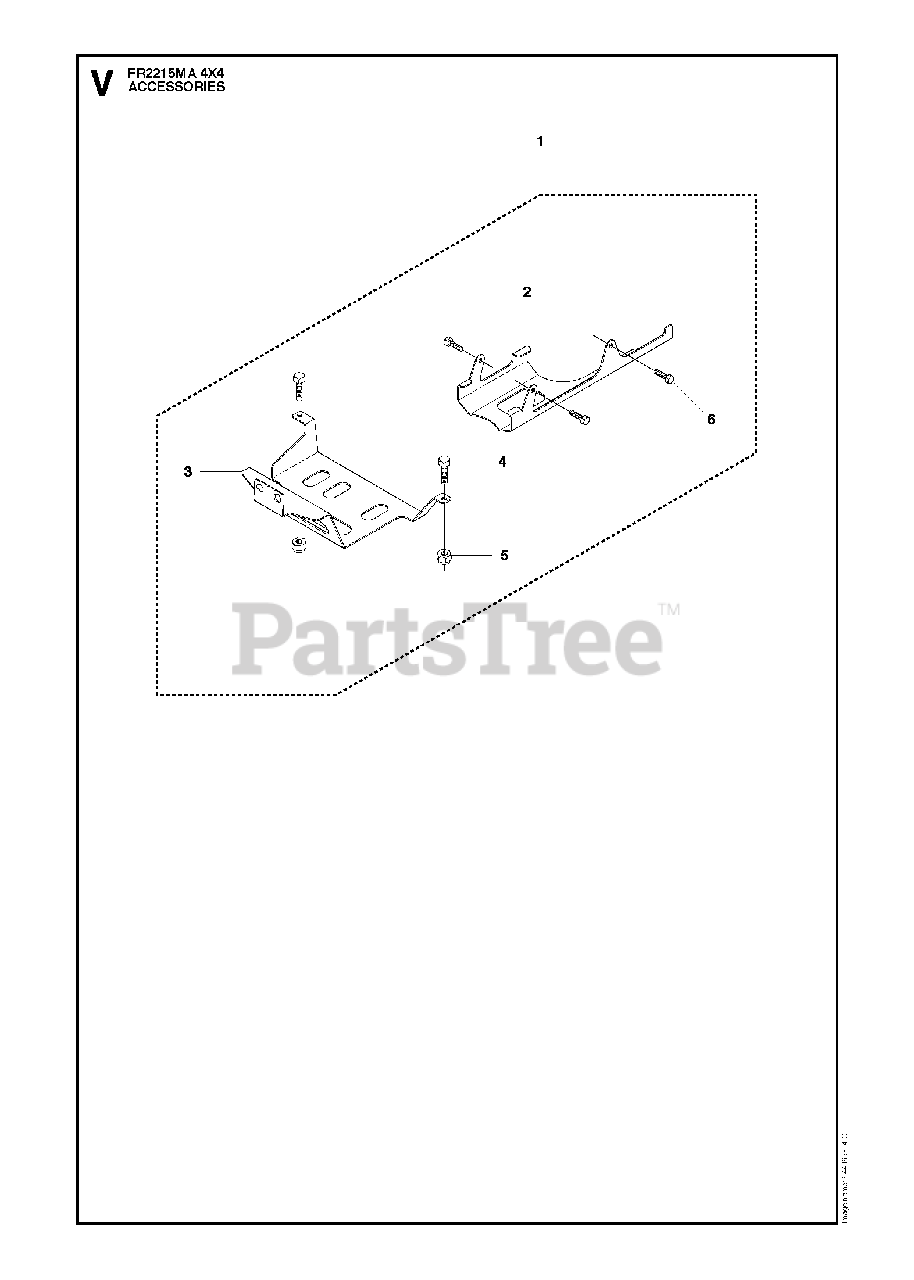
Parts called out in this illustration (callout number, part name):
2	KIT
3	RP PROTECTION PLATE REAR
4	SCREW
5	LOCKNUT M8
6	BOLT FLANGE - M8X16
